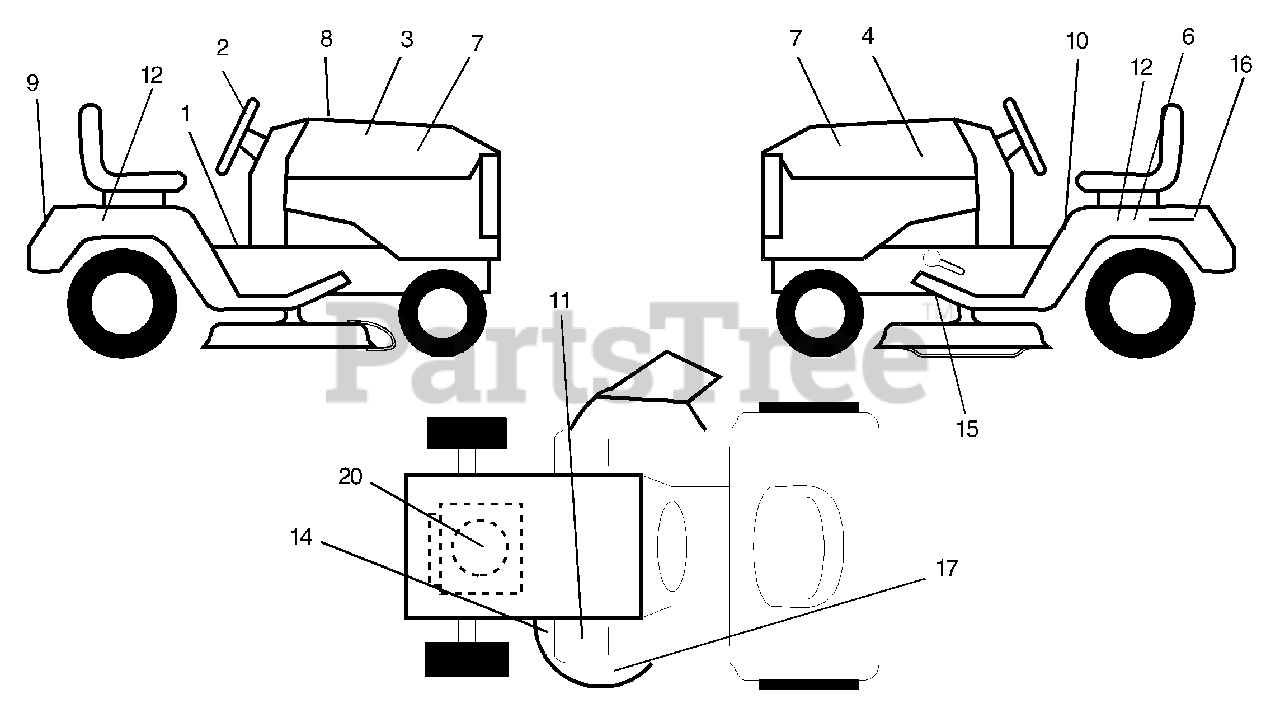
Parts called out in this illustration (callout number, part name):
1	Decal Instruction Operat English
2	Decal Ins Strg Wh
3	Decal Hood Rh
4	Decal Hood Lh
6	Decal, Battery Power Pro
7	Decal Panel Side
8	Decal Replacement Parts
9	Decal Fender Logo
10	Decal Danger English
11	Decal Clutch/brake English
12	Decal Fender
14	Decal V-belt Schematic 42"
15	Decal Schematic
16	Decal Battery Danger/Poison
17	Decal Deck Enviro
20	Decal HP Engine
